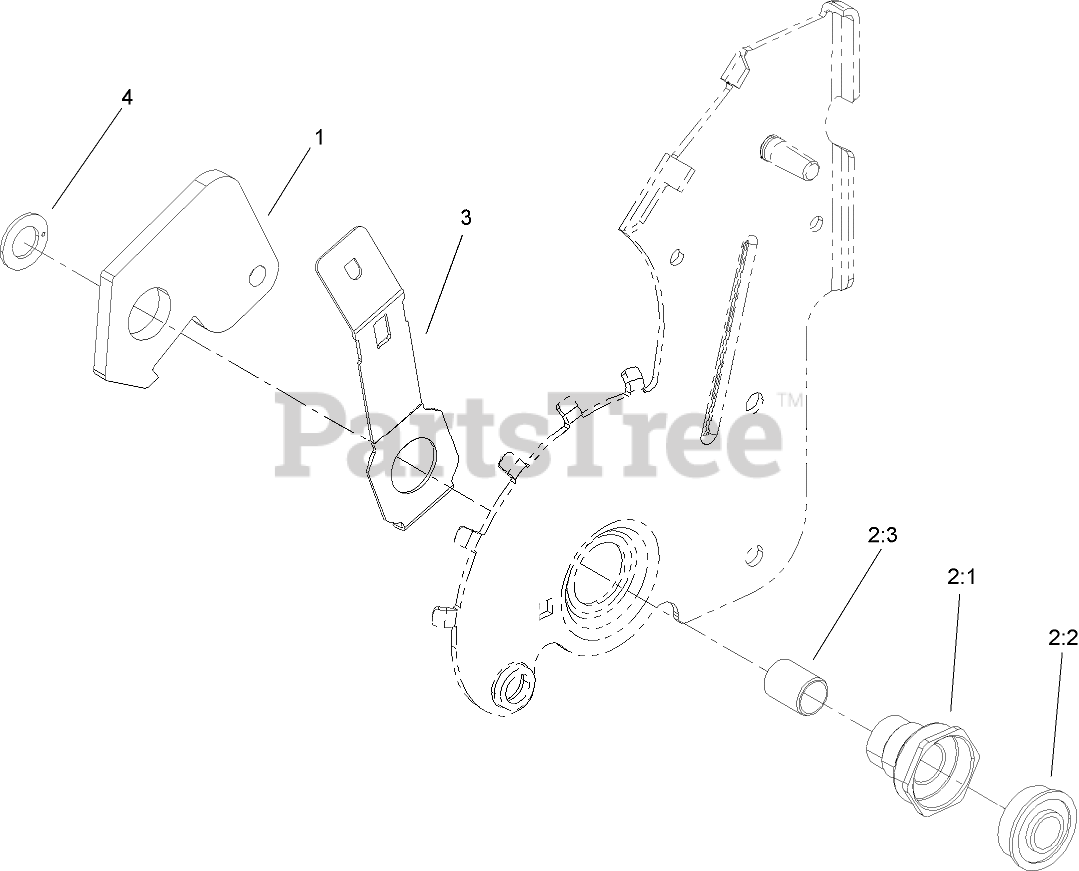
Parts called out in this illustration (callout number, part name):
1	ARM-PIVOT, REAR
2:1	RETAINER-BUSHING, HOC
2:2	BEARING-BALL
2:3	BUSHING-SLEEVE
3	ARM-SPRING
4	WASHER-THRUST
